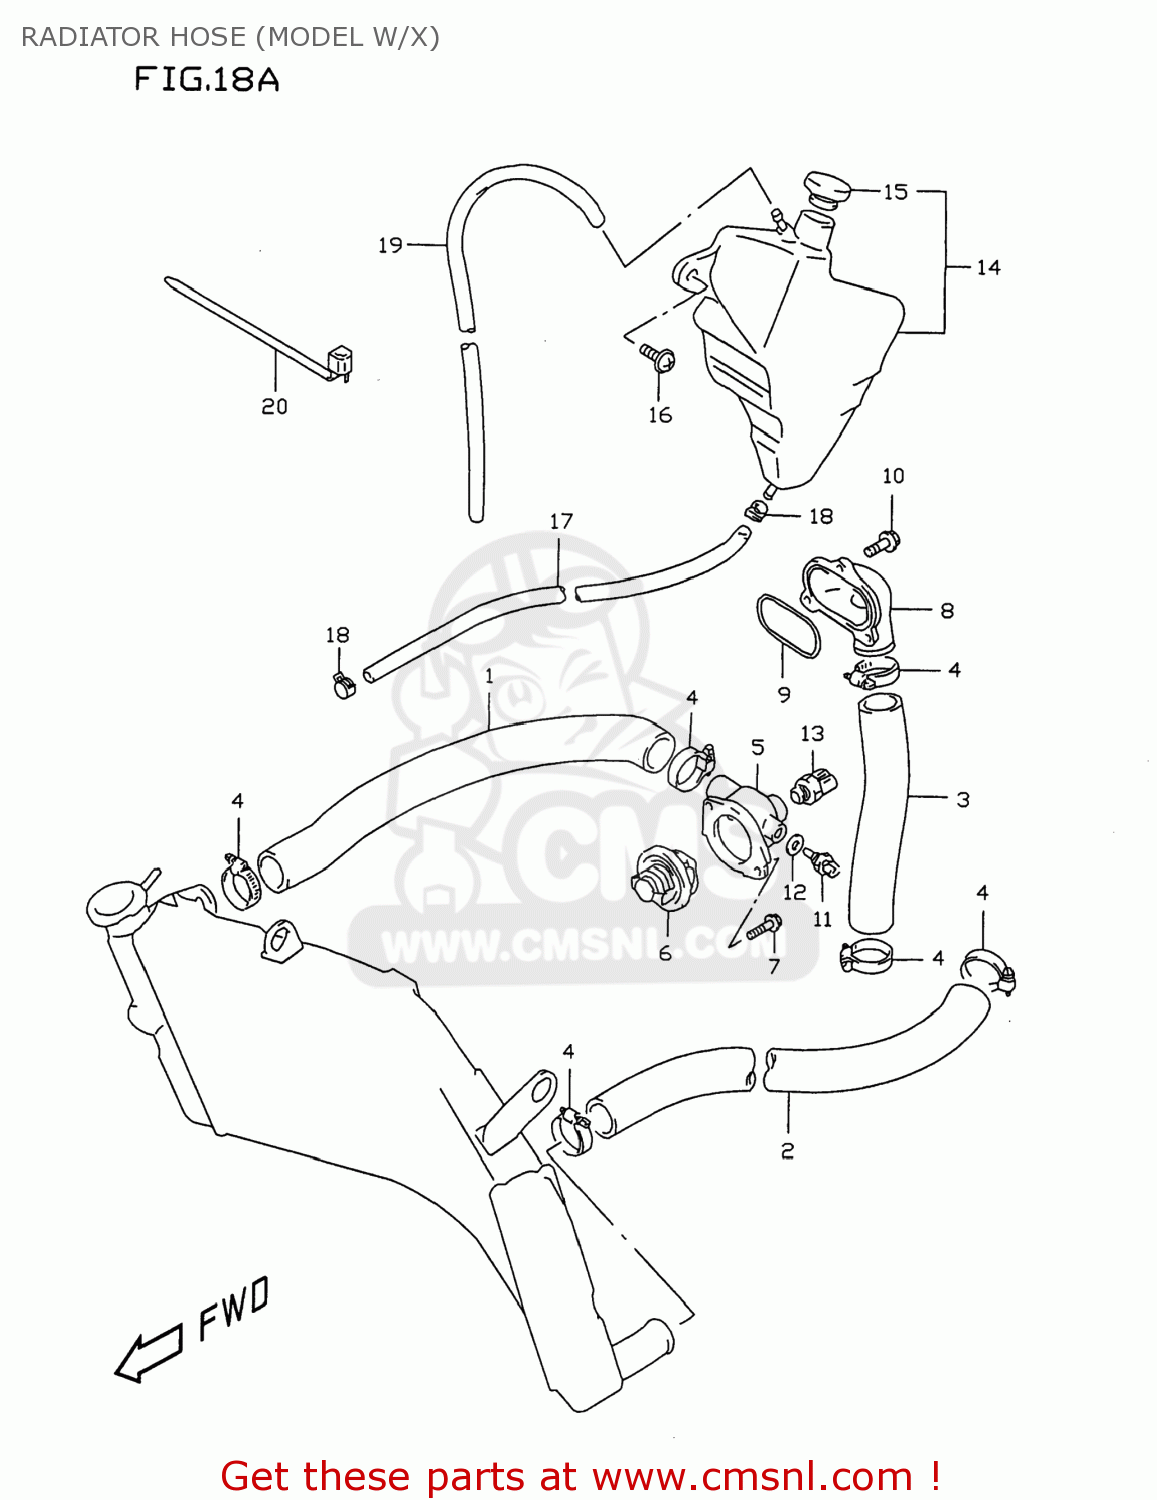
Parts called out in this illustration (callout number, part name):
1	HOSE,RADIATOR INLET
2	HOSE,RADIATOR OUTLET
3	HOSE,CYLINDER INLET
4	CLAMP
5	CAP,THERMOSTAT
6	THERMOSTAT,WATER
7	BOLT
8	CONNECTOR,CYLINDER WATER,INTAKE
9	O RING,CYL WATER CONNECTOR
10	BOLT
11	SENSOR,WATER TEMP
12	GASKET(12.2X21X0.8) (NAS)
13	SWITCH,RADIATOR FAN
14	TANK ASSY,RESERVOIR
15	CAP,RESERVOIR TANK
16	SCREW(6X20)
17	HOSE,RESERVOIR TANK INLET
18	CLIP
19	HOSE,RESERVOIR TANK OUTLET
20	CLAMP(L:165)
